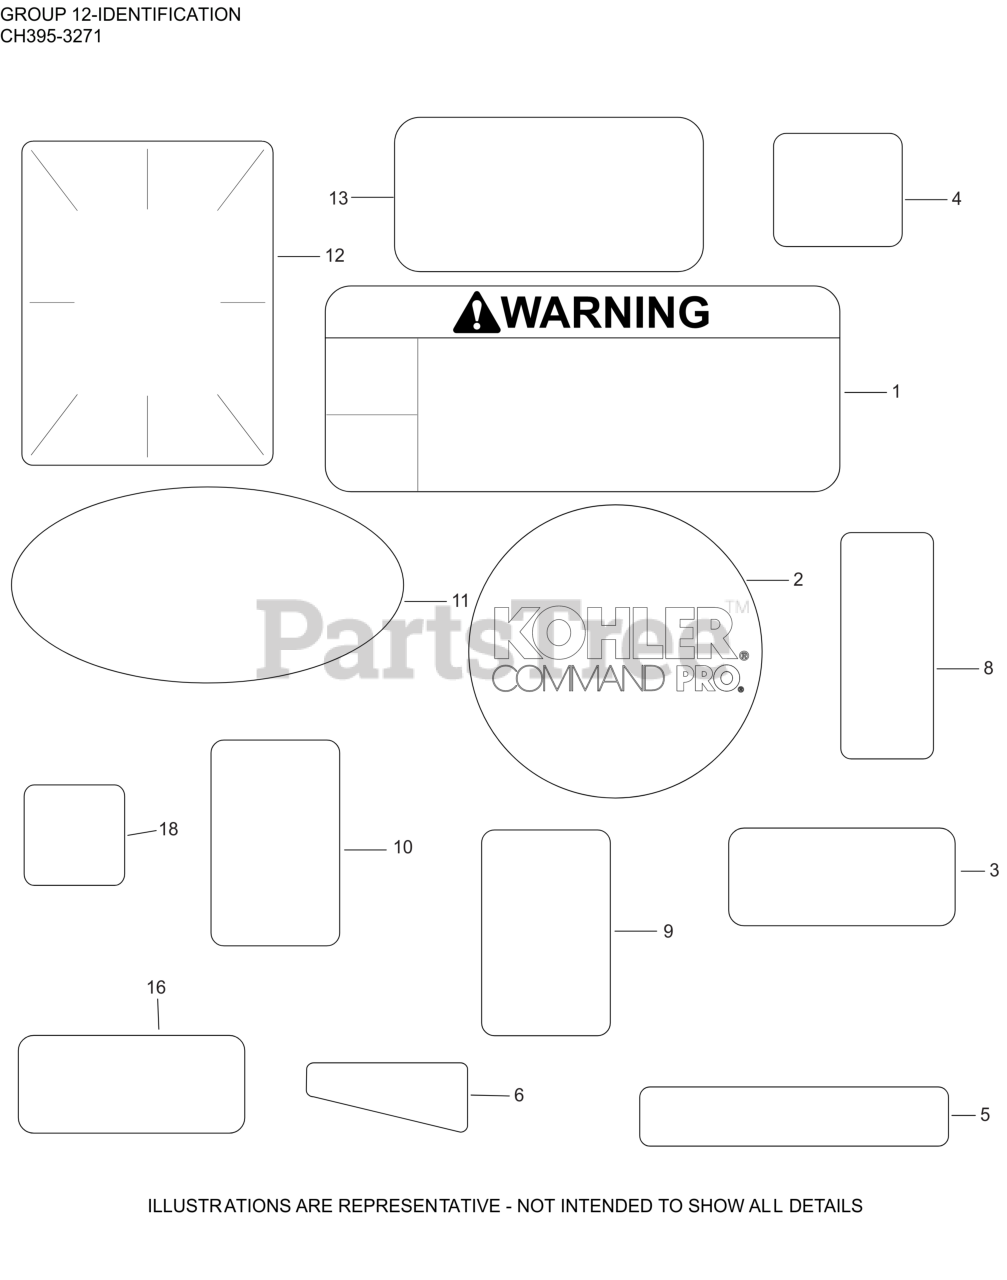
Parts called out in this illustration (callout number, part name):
1	DECAL, WARNING
2	LABEL, RECOIL 75MM
3	LABEL, CANADIAN COMPLIANCE
4	DECAL, BASE ARROW
5	DECAL, THROTTLE
6	DECAL, 9.5 HP/277cc/CH395
9	DECAL, SUN
10	DECAL, SNOW FLAKE
11	DECAL, QUAD CLEAN SILVER
12	LABEL, CLEAR LAMINATION
13	LABEL, MAINTENANCE (CKY)
16	DECAL, ETHANOL WARNING
18	LABEL, CHOKE
NI	LABEL, FUEL SECURE
